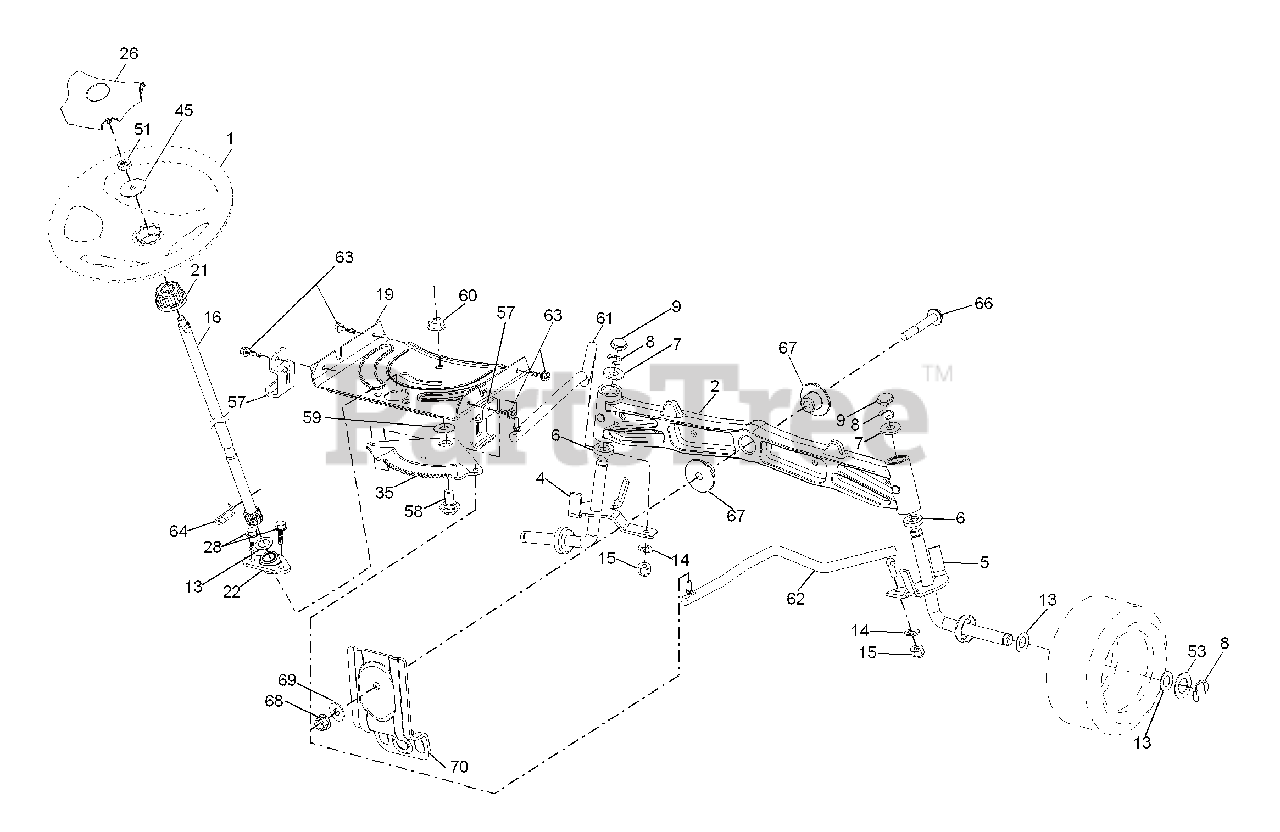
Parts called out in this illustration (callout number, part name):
1	Wheel, Steering
2	Axle Asm., Front
4	Spindle Asm., LH
5	Spindle Asm., RH
6	Bearing, Race Thrust Harden
7	Washer 25/32 x 1-5/8 x 16 Ga.
8	Ring, Klip #T5304-75
9	Cap, Spindle
13	Washer 25/32 x 1-1/4 x 16 Ga.
14	Washer, Lock Hvy Hlcl Spr 3/8
15	Nut, Crown Lock 3/8-24 unf
16	Shaft Steering
19	Plate Steering
21	Adapter, Wheel Steering
22	Bushing, Strg. Blk
26	Insert, Wheel Steering
28	Screw 3/8-16 x 3/4
35	Gear, Sector Plate
45	Washer 9/16 x 2-3/8 x 12 Ga.
51	Nut Hex Jam Toplock 1/2-20 unf
53	Washer Hardened .793 x 1.637 x.060
57	Bracket Upstop
58	Bolt Shoulder Sector Pivot CFM
59	Washer Thrust Sector Steering
60	Nut Flange Lock 5/8-11
61	Draglink LH
62	Draglink, RH
63	Screw 5/16-18 x 3/4
64	Retainer Clip Spring Steering
66	Bolt Hex Fghd 7/16-14 x 3 Serr
67	Bushing PM Front Axle
68	Nut Lock Flange 7/16-14 Gr. 5
69	Washer 1.5 x .505 x .118
70	Bracket Deck Susp. Front
